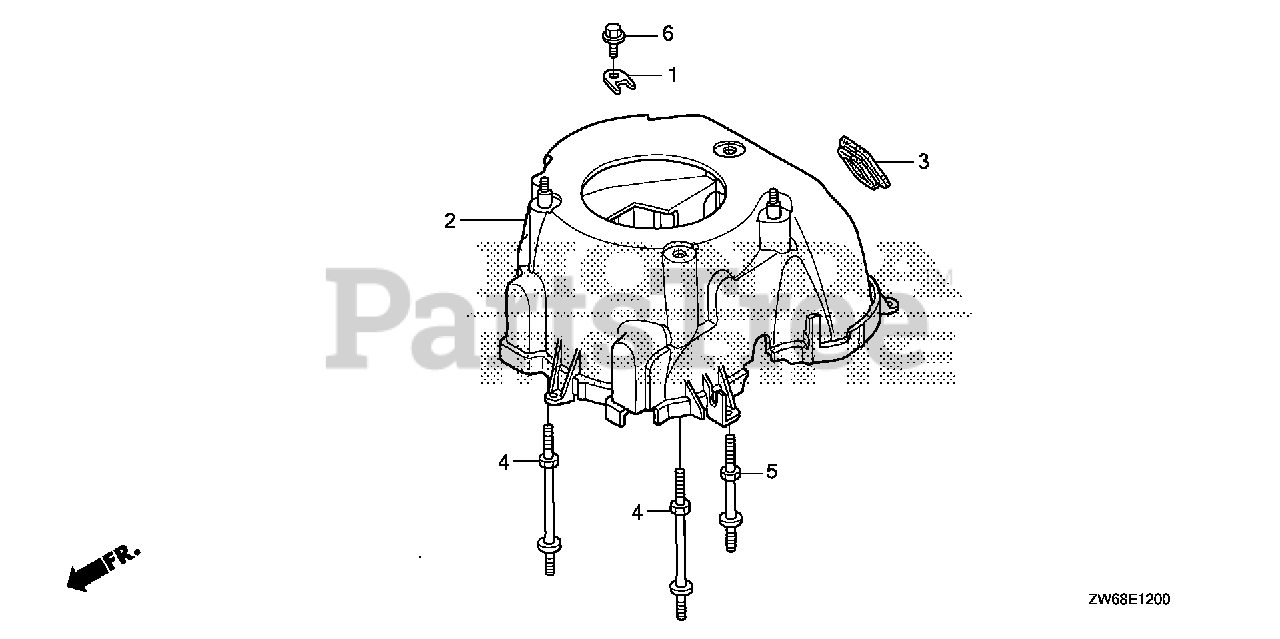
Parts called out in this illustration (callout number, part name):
1	HOLDER, CABLE
2	COVER, FAN
3	GROMMET, FAN COVER
4	BOLT A, STUD
5	BOLT B, STUD
6	BOLT, FLANGE (5X10)
